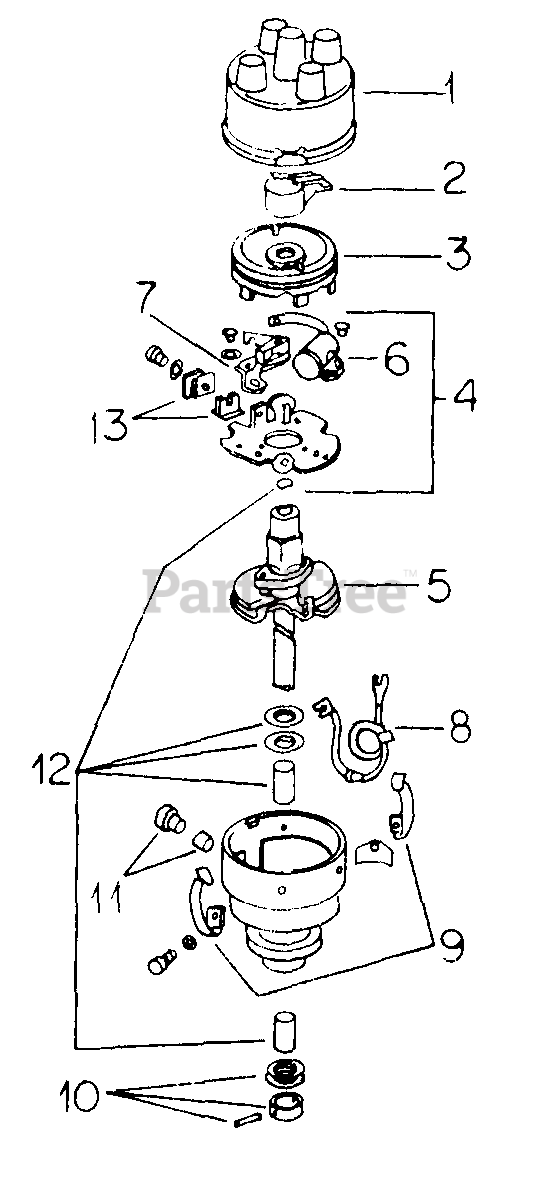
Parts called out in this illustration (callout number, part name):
1	CAP, DISTRIBUTOR
2	ROTOR, DISTRIBUTOR
3	COVER ASSY, DUST
4	PLATE ASSY, BREAKER
5	SHAFT ASSY, WEIGHT SPRING AND CAM
6	PACKAGE, CONDENSOR
7	PACKAGE, CONTACT BREAKER
8	LEAD ASSY, PRIMARY
9	PACKAGE, CAP CLAMP SPRING AND HINGE
10	PACKAGE, DRIVE GEAR
12	PACKAGE, SHAFT BEARING
13	PACKAGE, CLIP AND INSULATOR
